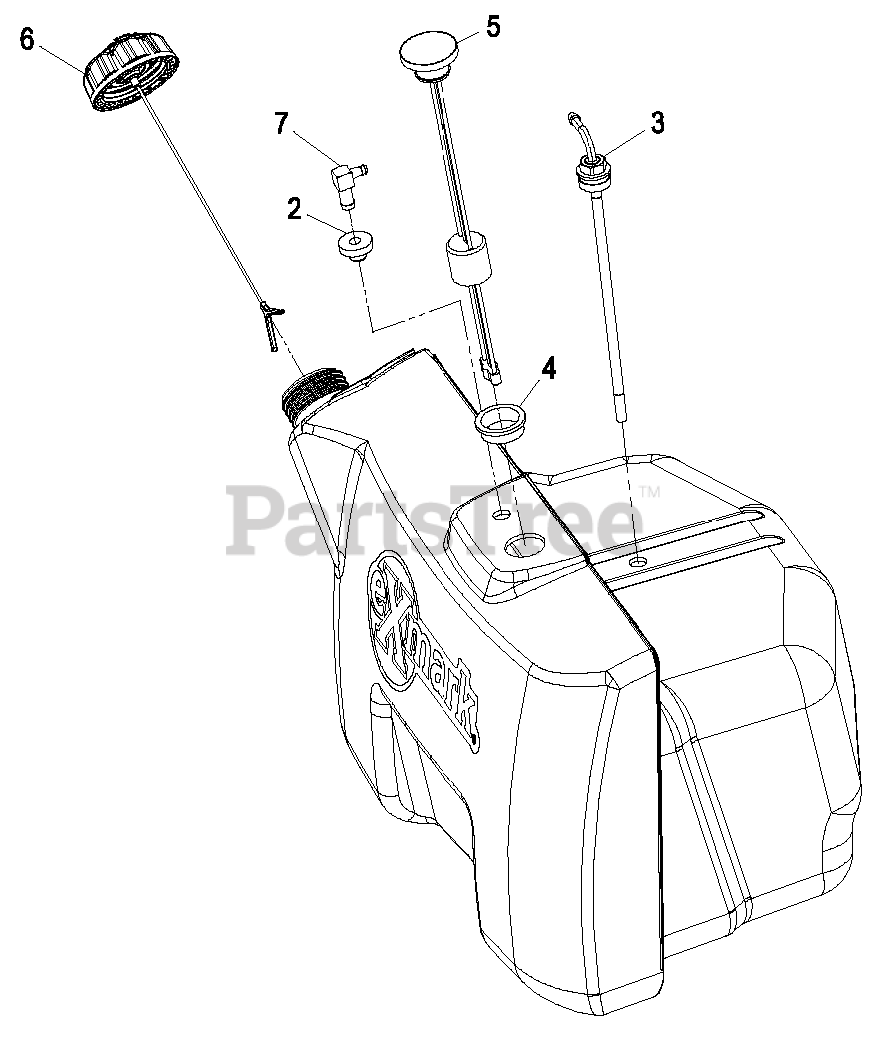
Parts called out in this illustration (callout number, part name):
2	BUSHING
3	FITTING-FUEL, BULKHEAD
4	CONTACT ORDER SERVICES
7	ELBOW-90 DEG
